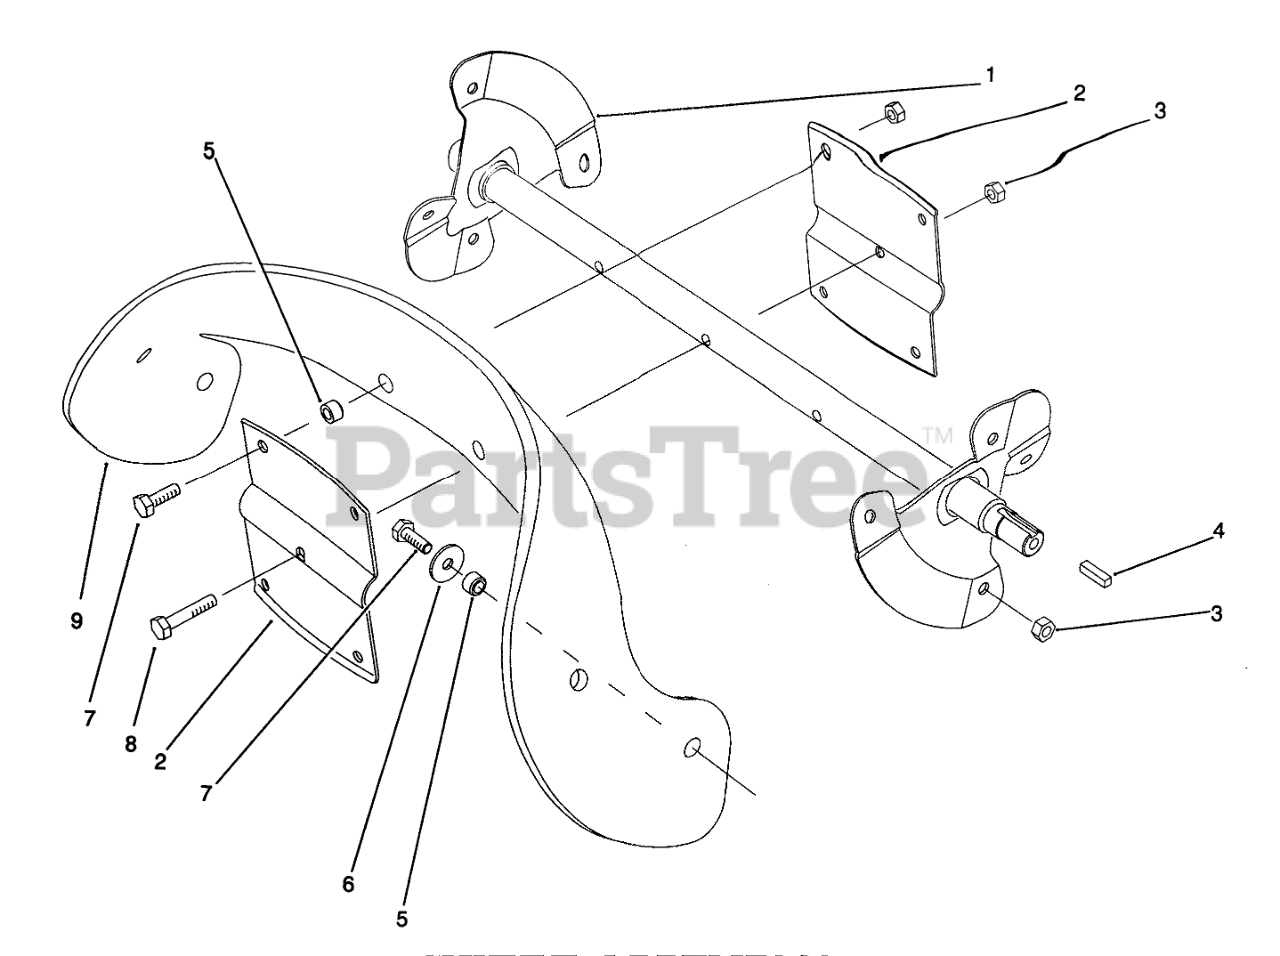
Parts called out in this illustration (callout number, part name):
1	Rotor Shaft Assembly
2	Rotor
3	NUT-LOCK, NI
4	KEY-SQUARE
5	SPACER-BLADE, ROTOR
6	WASHER-FLAT
7	SCREW-HH
8	SCREW-HH
9	Blade-Rotor
